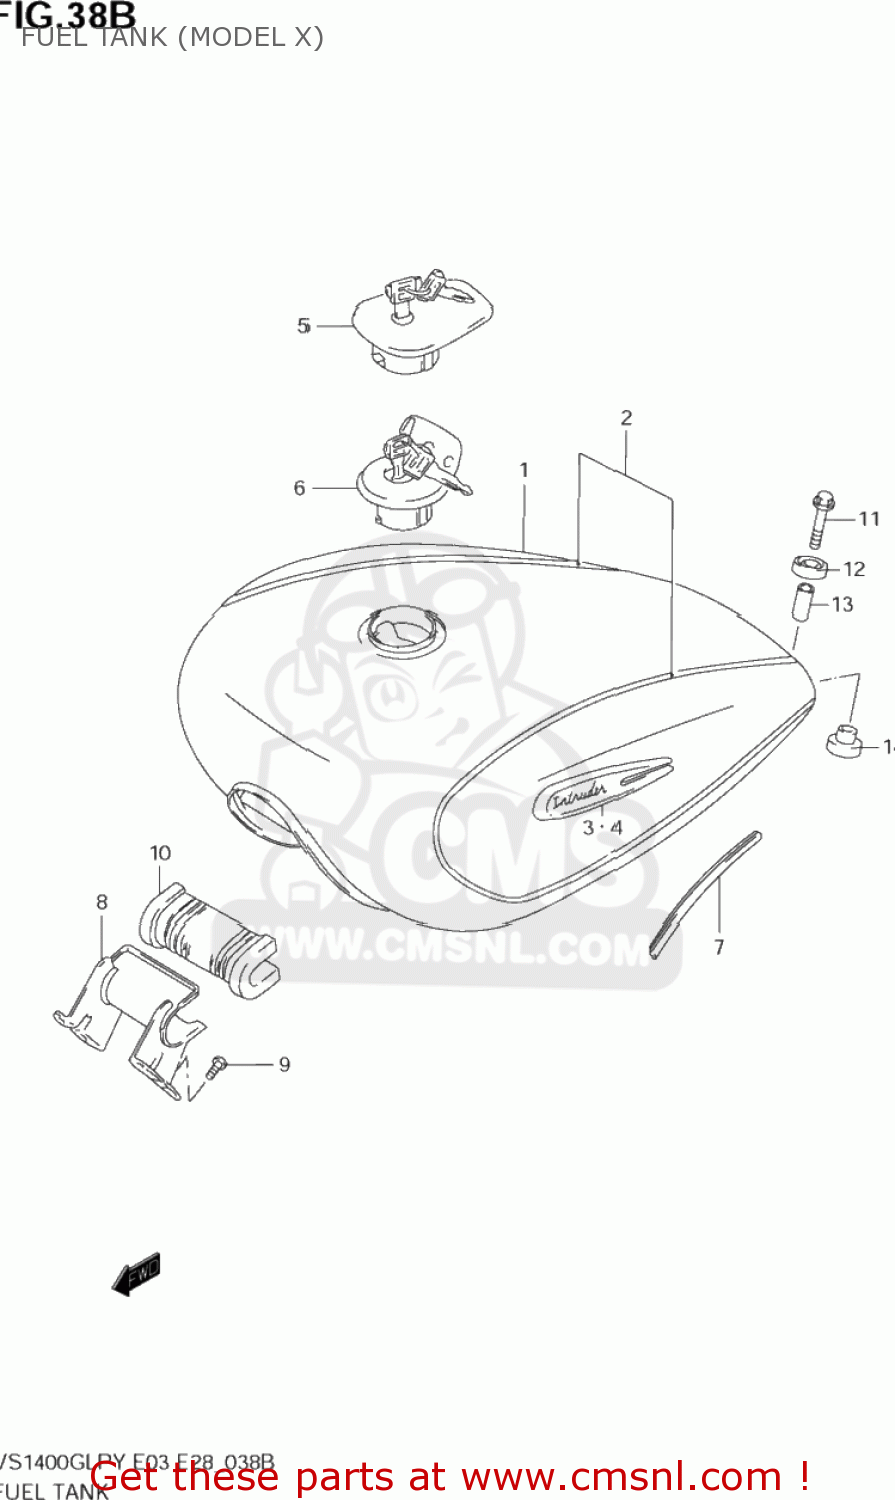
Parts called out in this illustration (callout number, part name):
1	TANK ASSEMBLY,FUEL
2	TAPE SET,FUEL TANK STRIPE
3	EMBLEM,FUEL TANK,R
4	EMBLEM,FUEL TANK,L
5	CAP SET,FUEL TANK
6	CAP SET,FUEL TANK
7	MOLDING
8	BRACKET,TANK
9	SCREW
10	CUSHION,FUEL TANK FR
11	BOLT
12	CUSHION
13	SPACER(6.5X9X22.5)
14	CUSHION
